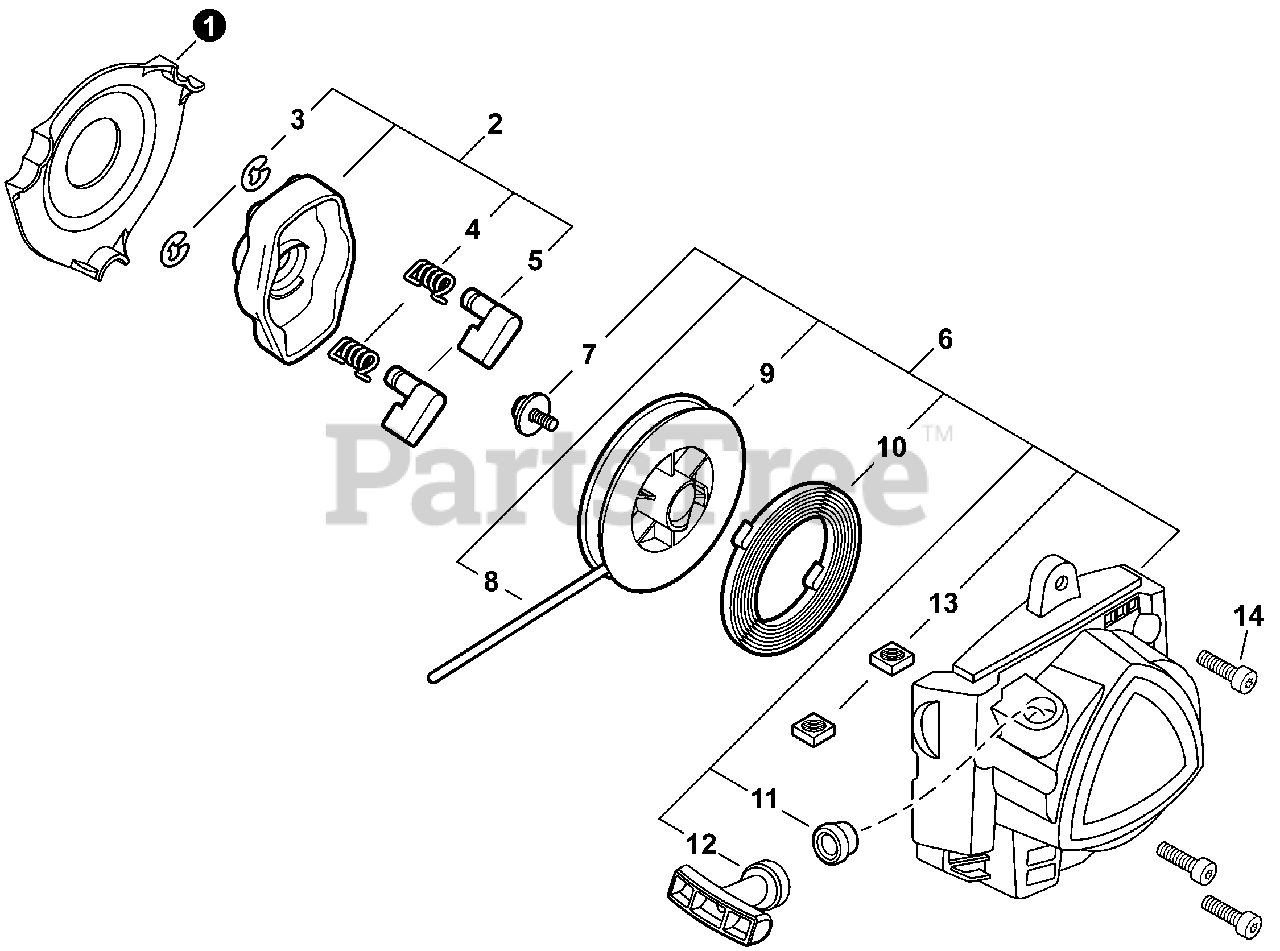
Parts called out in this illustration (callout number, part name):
1	COVER, DUST
2	PULLEY ASSY, STARTER
3	E-RING 4
4	SPRING, RETURN
5	PAWL, STARTER
6	STARTER ASSY, RECOIL
7	SCREW
8	ROPE, STARTER
9	REEL, ROPE
10	SPRING, RECOIL
11	GUIDE, ROPE
12	GRIP, STARTER
13	NUT M5
14	BOLT, TORX 5×16
